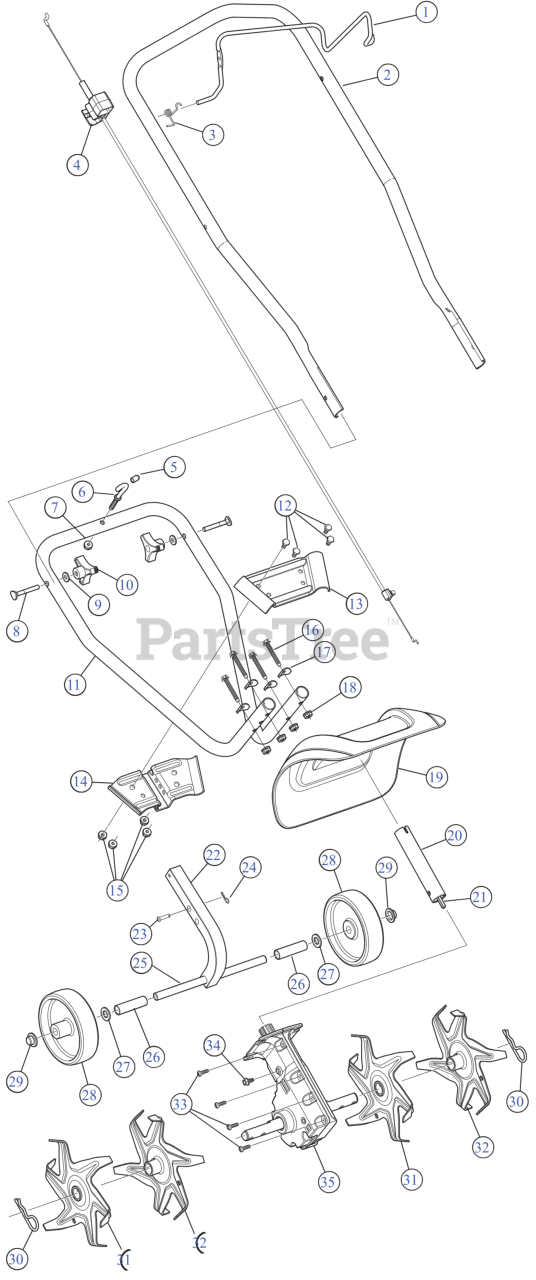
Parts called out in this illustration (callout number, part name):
1	BAIL CONTROL
2	HANDLE UPR
3	TORSION SPRING
4	THROTTLE CABLE
6	ROPE GUIDE
7	FLANGE LOCK NUT
8	BOLT, CARRIAGE CRV
9	SADDLE WASHER
10	KNOB, 3-PRONG ¼ "-
11	HANDLE LOWER
12	SCREW 1/4-20X.5 GR5
13	BRACKET UPR
14	BRACKET LOWER
15	LOCK NUT 1/4
16	SCREW 1/4-20 x 1.750
17	SADDLE WASHER
18	LOCK NUT 1/4
19	TINE SHIELD
20	BOOM ASSEMBLY
21	SHAFT-FLEX
22	TUBE SQUARE
23	CLEVIS PIN
24	COTTER PIN .072 DIA. 1.13 LG
26	SPACER
28	WHEEL:5.0 x 1.38
29	PUSH CAP
31	TINE ASSEMBLY (LH)I (RH)O
32	TINE ASSEMBLY (LH)O (RH)I
33	SCREW #
34	SCREW 1/4-20 X.500
35	GEARBOX ASSEMBLY CULT
